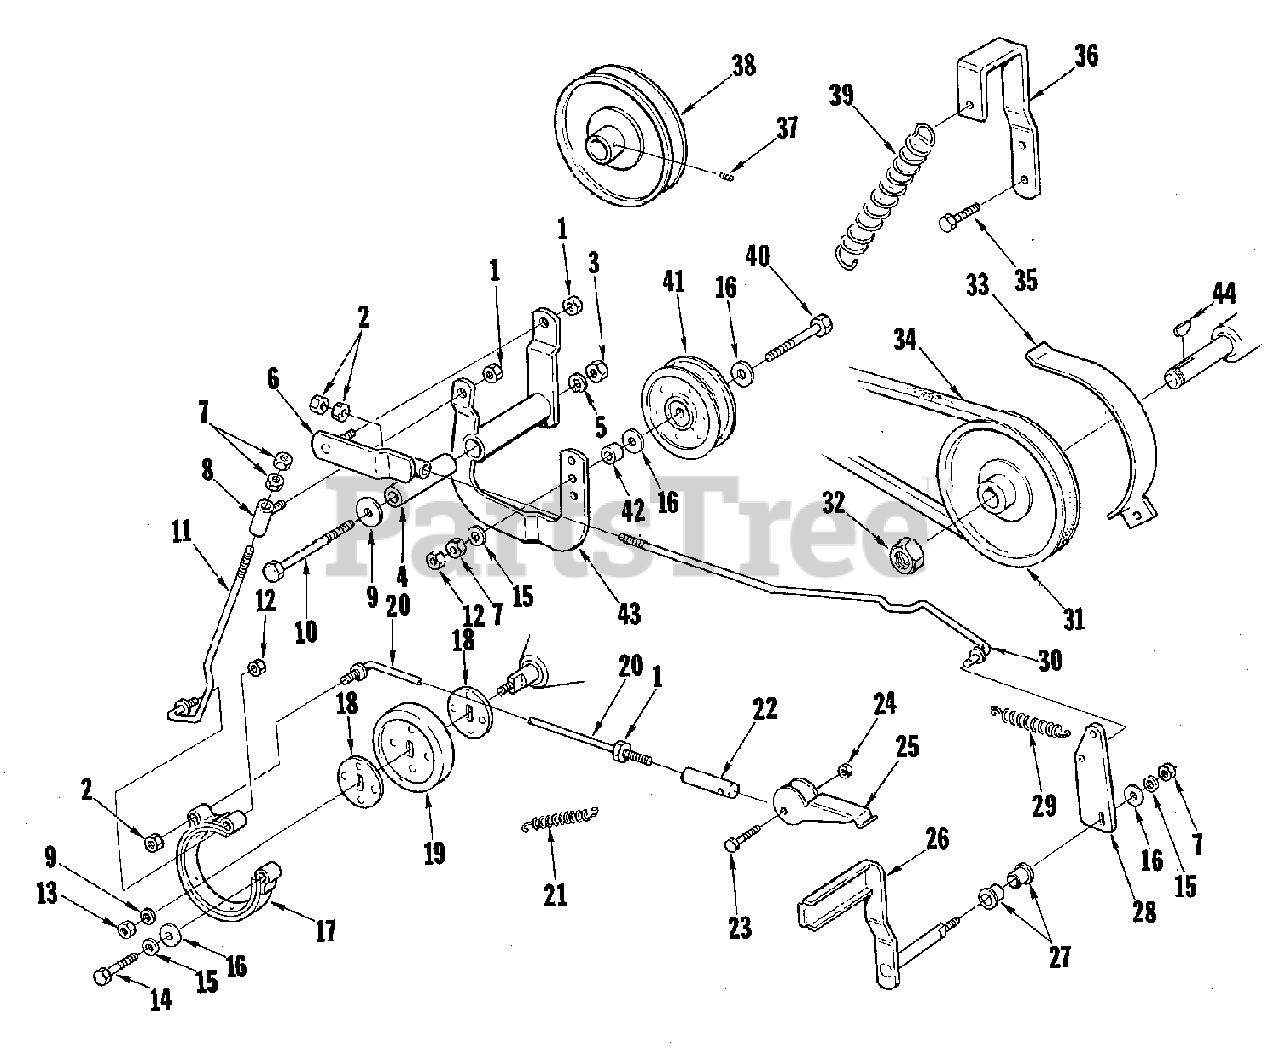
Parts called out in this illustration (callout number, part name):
1	NUT, Hex Lock, 5/16-18
2	NUT, Hex Fin, 5/16-18
3	NUT, hex Fin, 7/16-14
5	WASHER, Lock, 7/16
6	GUIDE ASSEMBLY, Rod
7	NUT, Hex Fin, 3/8-16
8	GUIDE ASSEMBLY, Rod
9	WASHER, Flat, 7/16
10	SCREW, Hex Head Cap, 7/16-14
11	ROD ASSEMBLY, Brake
12	NUT, Hex Lock Fin, 3/8-16
13	NUT, Hex Lock, 7/16-14
14	SCREW, Hex Head Cap, 3/8-16 x 1-3/4
15	WASHER, Lock, 3/8
16	WASHER, Flat, 3/8
17	BAND ASSEMBLY, Brake
18	WASHER, Special
20	ROD ASSEMBLY, Parking Brake
23	SCREW, Hex Head Cap, 1/4-20 x 1-1/4
24	NUT, Hex Lock, 1/4-20
25	LEVER, Parking Brake
26	PEDAL ASSEMBLY, Foot
27	BUSHING, Flanged
28	ARM, Foot Pedal
29	SPRING, Brake Pedal
30	ROD, Clutch & Brake
31	PULLEY, Driver
32	NUT, Jam Lock, 3/4-16
33	RETAINER ASSEMBLY, Belt
34	BELT, Hydrostatic Drive
35	SCREW, Tapping (Taptite), 3/8-16 x 3/4
36	BRACKET, Spring
37	SETSCREW, 5/16-18 x 5/16
38	PULLEY, Driven
39	SPRING, Idler Pulley
40	SCREW, Hex Head Cap, 3/8-16 x 2-1/4
41	PULLEY, Idler
43	LEVER ASSEMBLY, Idler
